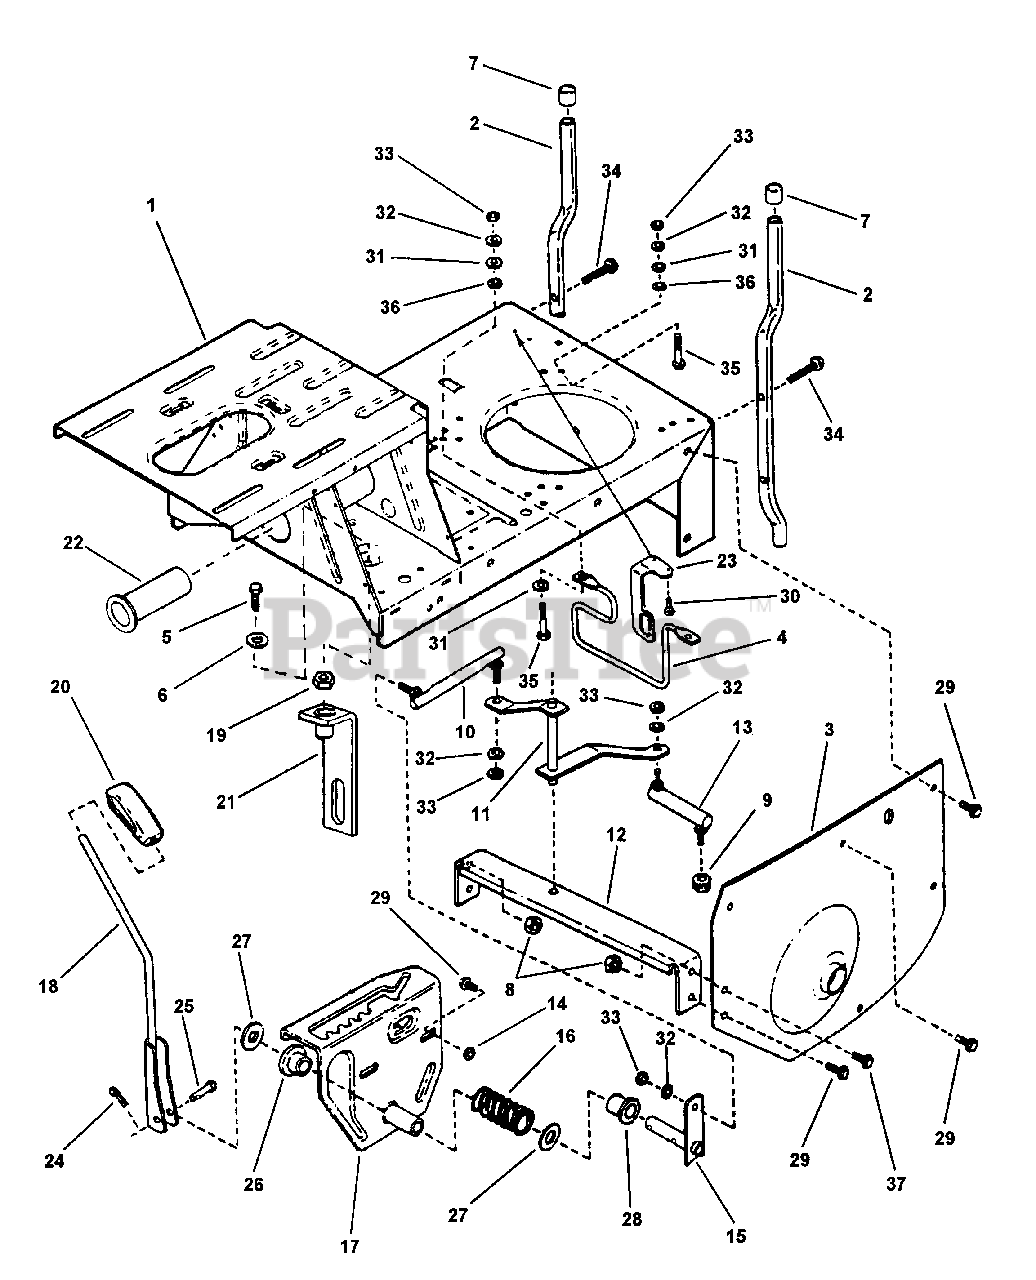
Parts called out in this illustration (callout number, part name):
1	CASE, Main (Standard)
2	BUMPER, Rear
3	FENDER, Left Hand
4	GUIDE, Belt
5	SCREW, 3/8-16 x 2" Hex Head Cap, Grade 5
6	WASHER, 3/8"
7	CAP, Bumper
8	NUT, 5/16-18 Hex Flange Lock
9	NUT, 5/16-24 Hex Flange Lock
10	LINK, Shift (Long)
11	ARM, Shift (Weldment)
12	BRACE, Cross
13	LINK, Shift (Short)
14	NUT, 5/16-18 Hex
15	ARM, Shift Handle (Weldment)
16	SPRING, Shift Handle
17	DETENT, Shift (Weldment)
18	HANDLE, Shift (Weldment)
19	NUT, 3/8-16 Hex
20	GRIP, Shift Handle
21	ASSEMBLY, Rear Hanger Deck
22	BUSHING, Pilot
23	BRACKET, Switch
24	PIN, 3/32 x 3/4" Cotter
25	PIN, 1/4 x 1-3/4" Tapered Clevis
26	BUSHING, Nylon
27	WASHER, Thrust
28	BUSHING, Nylon
29	SCREW, 5/16-18 x 5/8" Hex Washer Self-Tap
30	SCREW, 10-32 x 1/4" Hex Washer Self-Tap
31	WASHER, 5/16" Flat
32	WASHER, 5/16" Split Lock
33	NUT, 5/16-24 Hex
34	SCREW, 5/16-18 x 1-1/2" Hex Washer Self-Tap
35	SCREW, 5/16-24 x 1-1/2" Hex Head Cap
36	RETAINER, 5/16 Bolt
37	SCREW, 5/16-18 x 3/4" Hex Head Cap, Grade 5
